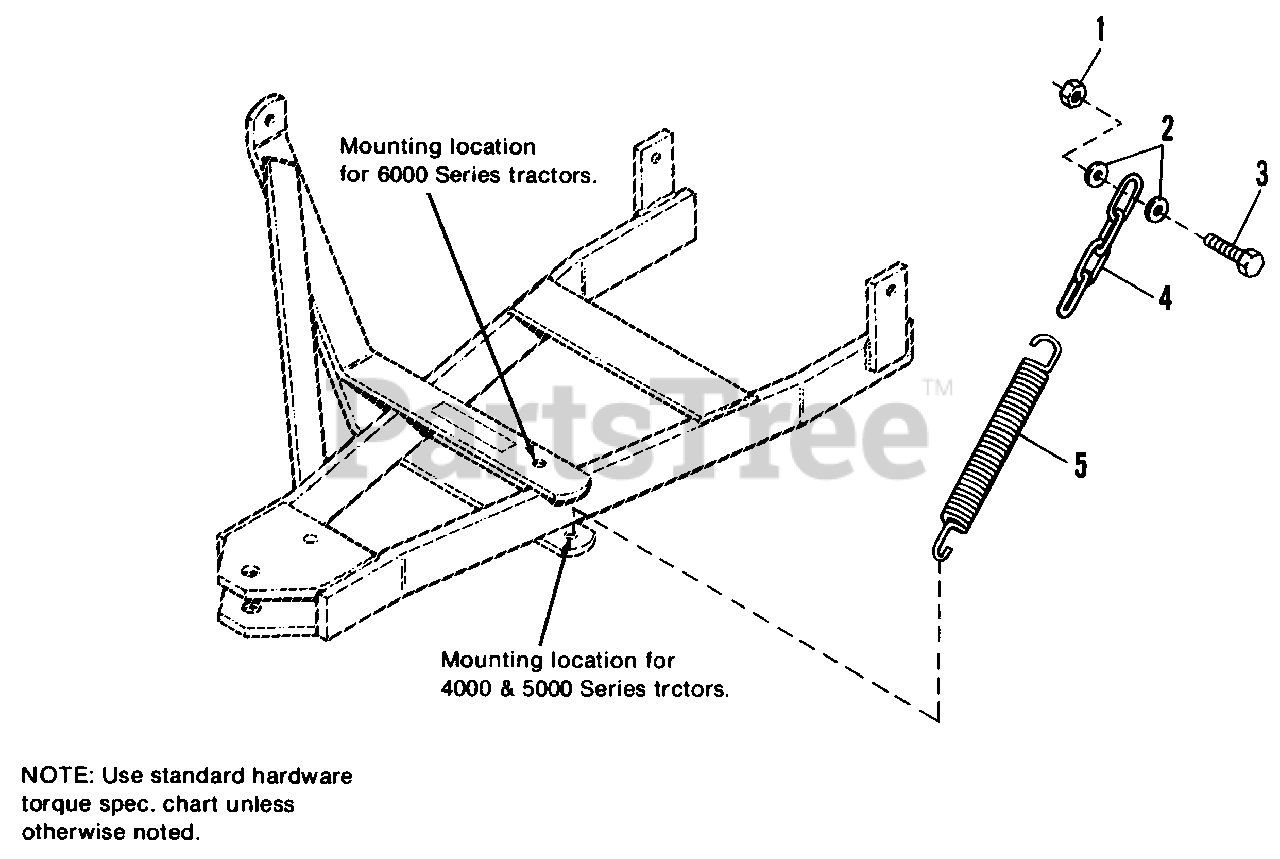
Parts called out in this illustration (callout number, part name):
1	NUT, Hex, Lock, 5/16-18
2	WASHER, Plain, 5/16
3	CAPSCREW, 5/16-18 x 1-1/4
4	CHAIN, 4-Links
